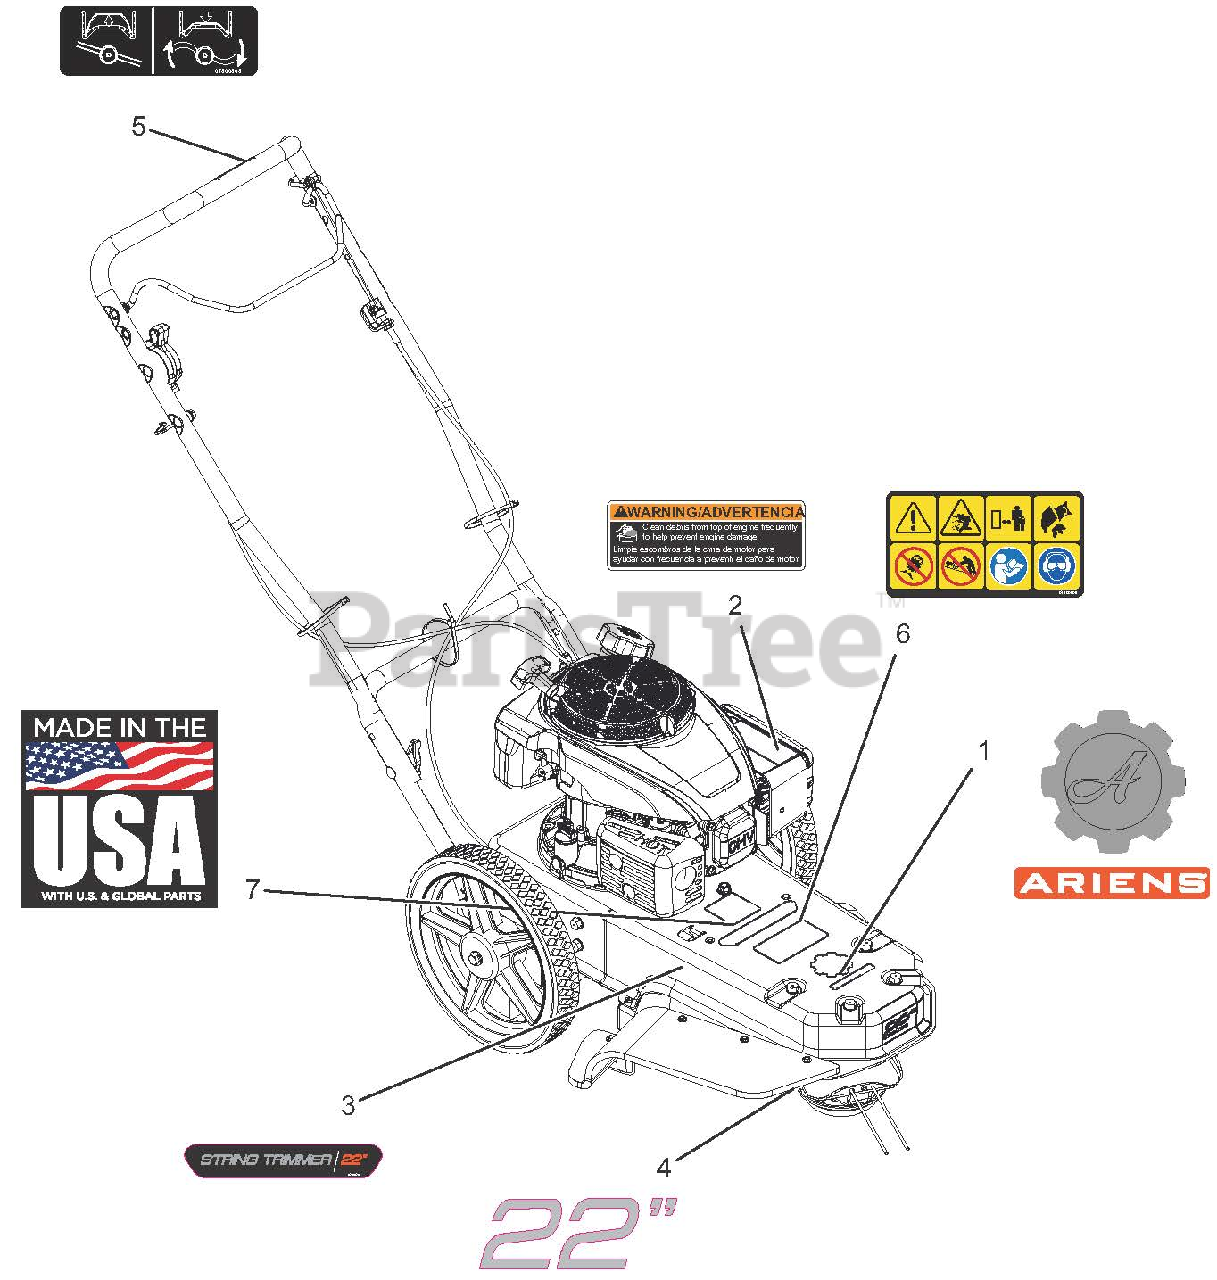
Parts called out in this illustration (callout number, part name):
1	DECAL-ARIENS
2	DECAL, TRIMMER DEBRIS WARNING
3	DECAL-STRING TRIMMER 22"
4	DECAL-22"
5	DECAL-OPERATOR PRESENCE
6	DECAL-DANGER
7	DECAL, MADE IN USA
